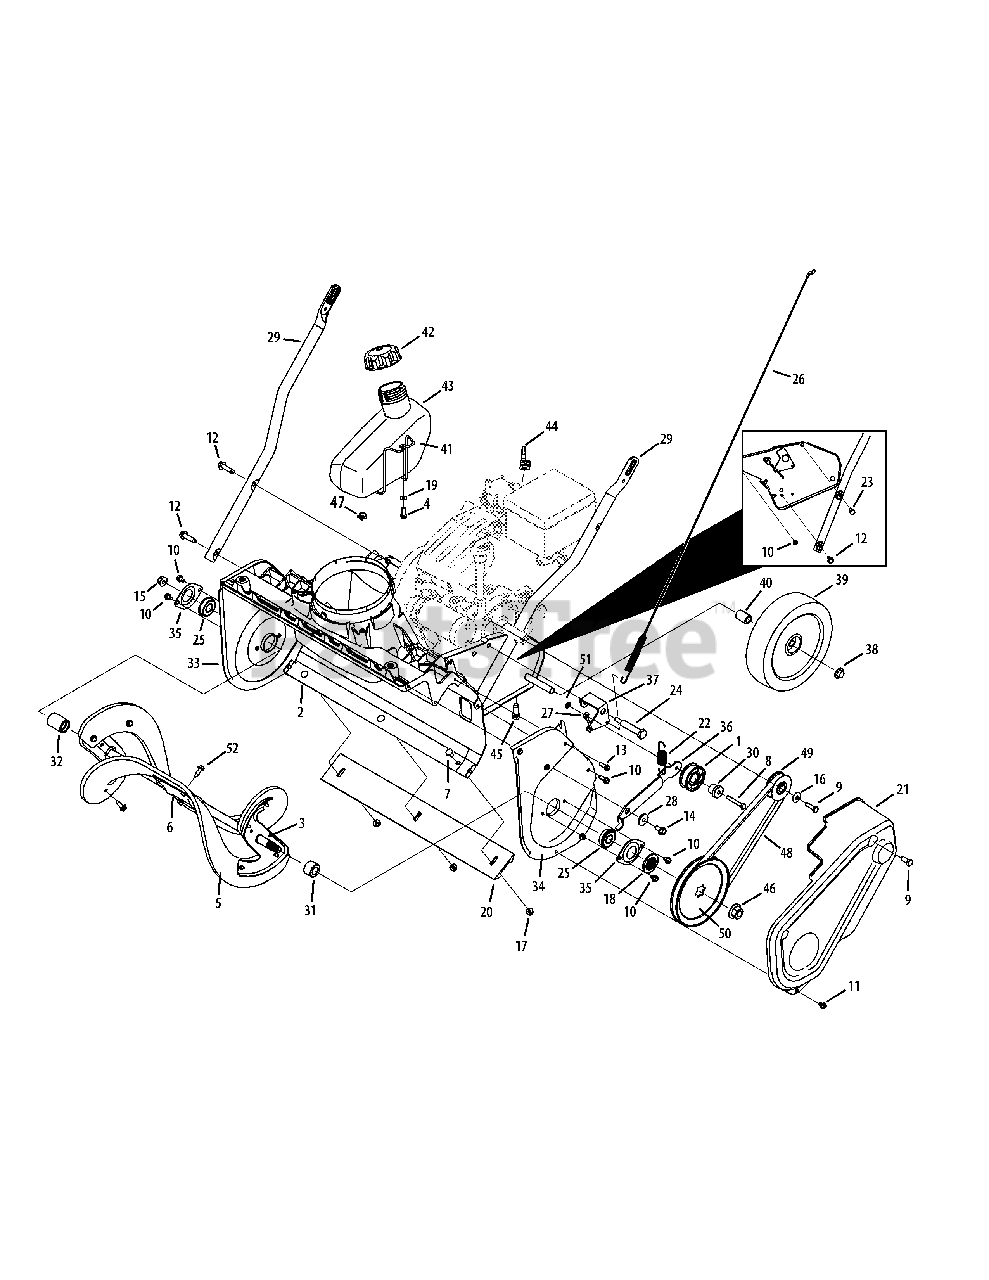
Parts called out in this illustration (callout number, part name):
1	Idler Pulley Assembly
2	Frame
3	Auger Assembly Complete
3	Auger Assembly Axle w/o paddles and center auger bracket
4	Screw, 1/4-10 x .625
5	Auger Replacement Kit
6	Center Auger Bracket
6	Hex Washer Screw 1/4-20 x.750
7	Carriage Screw, 1/4-20 x .62
8	Hex Screw, 1/4-20 x 1.50
9	Hex Lock Screw, 5/16-24 x .875
10	Hex Washer Screw, 1/4-20 x .625
11	Hex Washer Screw, 1/4-20 x .500
12	Hex Washer Screw, 5/16-18 x 1.250
13	Hex Washer Screw, 1/4-15 x .750
14	Hex Washer Screw, 5/16-18 x .75
15	Flange Lock Nut, 3/8-16
16	Thrust Washer, .330 x 1.25 x .120
17	Flange Lock Nut, 1/4-20
18	Pulley Hub
19	Washer, .265 x 1.00 x .030
20	Shave Plate
21	Belt Cover
22	Extension Spring, .70 x 3.035
23	Hex Screw, 5/16-24 x 1.25
24	Shoulder Bolt, 5/16-24 x .496 x 2.18
25	Ball Bearing, .500 x 40mm x 12mm
26	Clutch Cable
27	Drive Cable Wire Support
28	Shoulder Spacer
29	Lower Handle
30	Shoulder Spacer, .260 x .785 x .538
31	LH Auger Spacer
32	RH Auger Spacer
33	RH Auger Plate
34	LH Auger Plate
35	Bearing Cup
36	Idler Bracket
37	Cable Idler Bracket
38	Push Cap, 1/2
39	Wheel, 7"
40	Spacer, .525 x .775 x .835
41	Gas Tank Wire Support
42	Fuel Cap
43	Fuel Tank
44	Choke Extension Lever
45	Hex Washer Screw, 3/8-16 x 1.000
46	Flange Nut, 7/16-20
47	Hose Clamp
48	Belt, .500 x 35.06
49	Pulley Half, .625 x 2.25
50	Pulley, 1/2 x 6.00
51	Push Nut
52	Hex Washer Screw, 1/4-20 x .750
